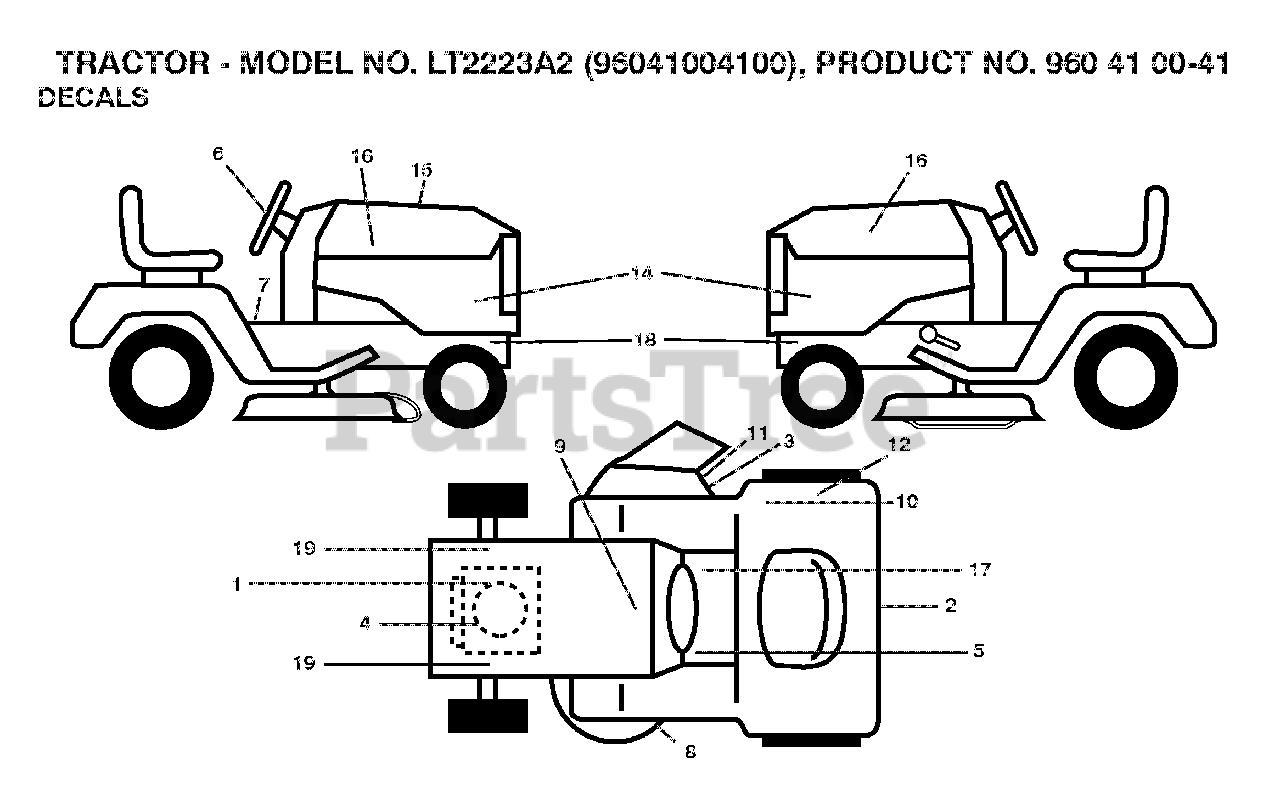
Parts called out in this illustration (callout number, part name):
1	DECAL.B&S.900.TANK.REF.276991
3	DECAL, DEFLECT WARNING
8	DECAL.MOWER.SCH.48/54
9	DECAL BTRY SYMBOLS
10	DECAL.FENDER
11	DECAL.INTERNATIONL.CUTFINGER
17	DECAL PARK BRAKE
